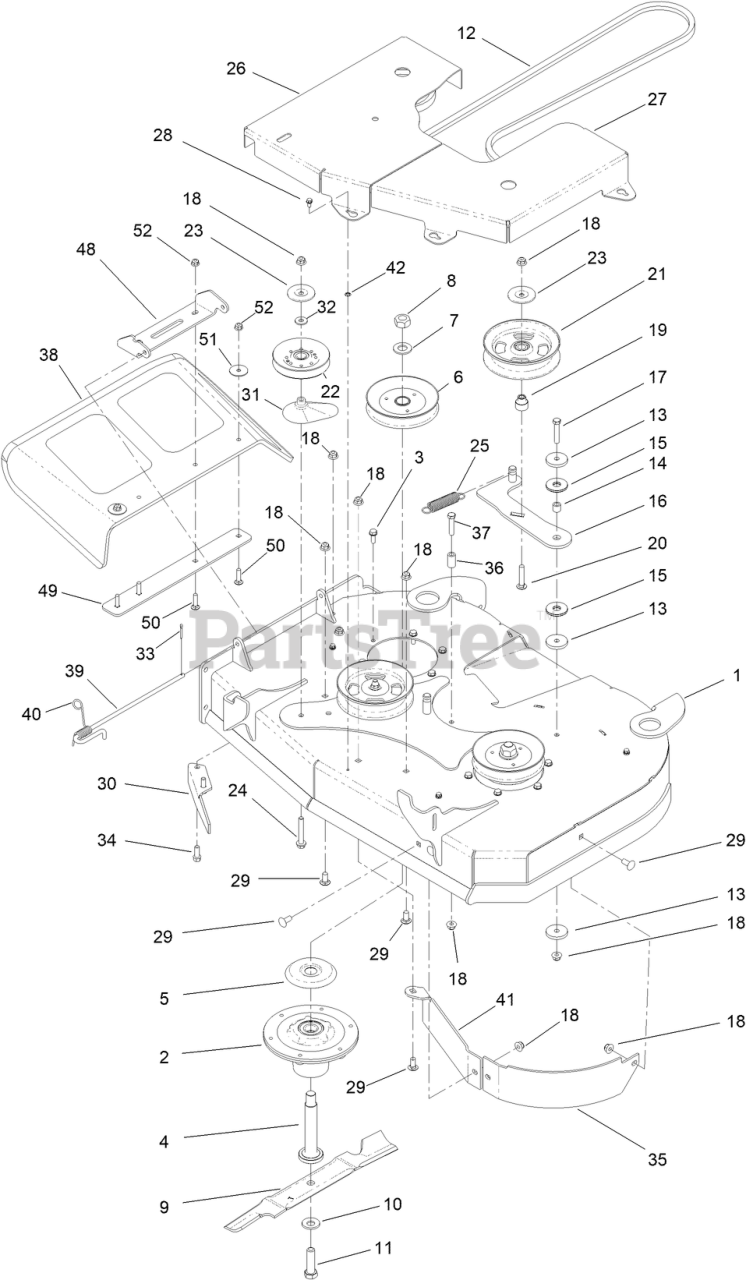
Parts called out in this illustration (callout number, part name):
1	DECK ASM-36"
2	SPINDLE ASM
3	SCREW-TAPTITE
4	SHAFT-SPINDLE
5	SHIELD-BEARING
6	PULLEY
7	WASHER
8	NUT-HEX
9	BLADE - HI FLOW, 18.00 IN
10	WASHER-BELLEVILLE
11	SCREW-BLADE
12	BELT-V
13	WASHER-PLAIN
14	BUSHING-IDLER
15	WASHER-FRICTION, COMPOSITE
16	IDLER ARM ASM
17	SCREW-HH
18	NUT-HF, NI
19	BUSHING-IDLER
20	SCREW-CARR
21	PULLEY-IDLER, FLAT
22	IDLER - V 4.13 EOD-A
23	SHIELD-DUST
24	SCREW-HHF
25	SPRING-EXTENSION
26	COVER-DECK
27	COVER-DECK
28	SCREW-HWH
29	SCREW-CARR
30	BAFFLE-DISCHARGE
31	SPACER-PULLEY
32	WASHER-HARDENED
33	PIN-COTTER
36	SPACER-FENDER
37	SCREW-HH
38	DEFLECTOR
39	PIN-CHUTE
40	SPRING-TORSION
41	PLATE-DEFLECTOR
42	NUT-RETAINING
48	BRACKET UPPER, DEFLECTOR
49	PLATE-DEFLECTOR
50	SCREW-CARR
51	WASHER-FLAT
52	NUT-HF, NI
